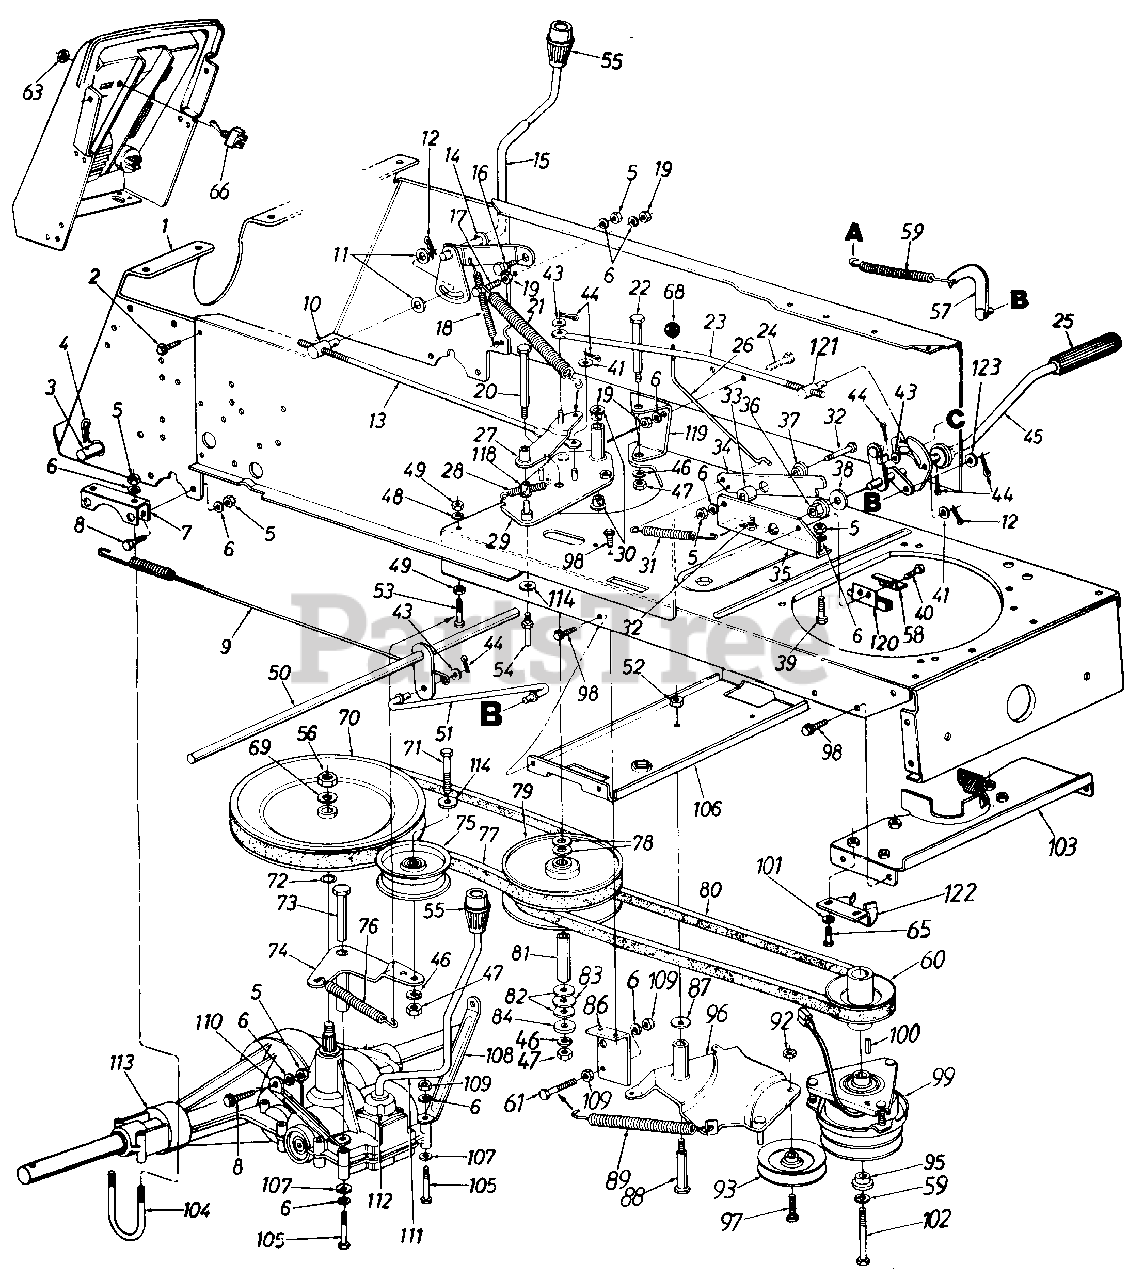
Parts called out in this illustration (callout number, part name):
3	Hitch Rod
4	Hitch Pin Clip
5	Hex Nut 5/16-18 Thd.
6	L-Wash. 5/16" I.D.
7	Transaxle Bracket
8	Hex Bolt 5/16-18 x .75" Lg. (Grade 5)
9	Brake Extension Spring
10	Adjustment Ferrule 3/8-24 Thd.
11	Fl-Wash. .385" I.D. x .87"
12	Internal Cotter Pin
13	Speed Control Link
14	Fl-Wash. .531" I.D. x .94"
15	Speed Selector Lever Ass'y.
16	Shld. Bolt .437" Dia. x .162"
17	Hex Bolt 5/16-24 x 1.25" Lg.
18	Extension Spring 3.9" Lg.
19	Hex Nut 5/16-24 Thd. (Grade 5)
20	Hex Bolt 3/8-24 x 4.5" Lg.
21	Extension Spring 11" Lg.
22	Shld. Bolt .625" Dia. x 3.5" Lg.
23	Speed Control Link
24	Hex Bolt 5/16-24 x .75" Lg.
25	Foot Pad
26	Parking Brake Link
29	Pulley Plate Ass'y.
30	Flanged Brg. .63" I.D.
31	Extension Spring 2.51" Lg.
32	Hex Bolt 5/16-18 x 1.25" Lg.
33	Spacer .34" I.D. x .88"
36	Hex Flange Brg. .634" I.D.
37	Shld. Spacer .5" Dia.
38	Fl-Wash. .64" I.D. x 1.24"
39	Hex Bolt 5/16-18 x .75" Lg.
40	Hex Tap Scr. #10-32 x 5/8" Lg.
41	Fl-Wash. .406" I.D. x .75" O.D.
43	Fl-Wash. .34" I.D. x .68" O.D.
44	Cotter Pin 3/32" Dia.
47	Hex Nut 3/8-24 Thd.
48	L-Wash. 1/4" I.D.
49	Hex Nut 1/4-20 Thd.
50	Brake Link Bracket
51	Front Brake Rod Link
52	Hex Cent. L-Nut 3/8-16 Thd.
53	Hex Bolt 1/4-20 x 2.0" Lg.
54	Belt Guard Pin
55	Shift Knob
56	Hex Jam Nut 9/16-18 Thd.
57	Foot Pedal Brkt. Ass'y.
58	Switch Plate
59	Ext. Spring 5.2" Lg. L-Wash. 7/16" I.D.
60	Engine Pulley
61	Hex Bolt 5/16-24 x 1.75" Lg.
63	Hex Nut 1/2-27 Thd.
65	Hex Bolt 5/16-18 x .75" Lg. (Grade 5)
66	Toggle Switch
68	Ball Knob Brake
69	Bell-Wash. 9/16" I.D. x 1.25"
70	V-Pulley 91/4" O.D.
71	Hex Bolt 3/8-24 x 1.75" Lg.
72	Wire Ring
73	Shld. Bolt 5/16-24 Thd.
74	Idler Brkt. Ass'y.
75	Flat Idler 3.5" O.D.
76	Extension Spring 6.12" Lg.
77	V-Belt
78	Teflon Washer 1.20" O.D.
79	Variable Speed Pulley 6" Dia.
80	V-Belt
81	Pivot Bushing
82	Fl-Wash. .56" I.D. x 1.0" O.D.
83	Thrust Brg. .56" I.D. x 1.25"
84	Retainer Cup
86	Parking Brake Mtg. Brkt.
87	Bell-Wash. .38" I.D. x .88" O.D.
88	Shld. Bolt .498" Dia. x 2.05"
89	Extension Spring 4.0" Lg.
92	Hex Cent. L-Nut 3/8-24 Thd.
93	V-Belt Idler
95	Shoulder Spacer
96	Idler Brkt. Deck Ass'y.
97	Hex Bolt 3/8-24 x 1.5" Lg.
98	Hex TT-Tap Scr. 1/4-20 x .5"
99	Electric Ciutch
100	Sq. Key 1/4 X 1.5" Lg.
101	Bell-Wash. .345" I.D. x .88"
102	Hex Bolt 7/16-20 x 3.75" Lg.
103	Belt Keeper Brkt. Ass'y.
104	U-Bolt
105	Hex Bolt 5/16-24 x 2.25" Lg.
106	Deck Idler Support Brkt.
107	Fl-Wash. .344" I.D. x .62" O.D.
108	Front Trans. Support Brkt. L.H.
109	Hex Nut 5/16-24 Thd.
110	Front Trans. Support Brkt. R.H.
111	Shift Lever Ass'y. Complete
112	Socket Hd. Cap Scr. #10 x 24
113	2-Speed Transmission Comp.
114	Fl-Wash. 3/8" I.D. x 1.0" O.D.
118	Nyliner Flanged Brg.
119	Variable Speed Support Brkt.
120	Safety Switch (Clutch)
121	Adjustment Ferrule 3/8-24 Thd.
